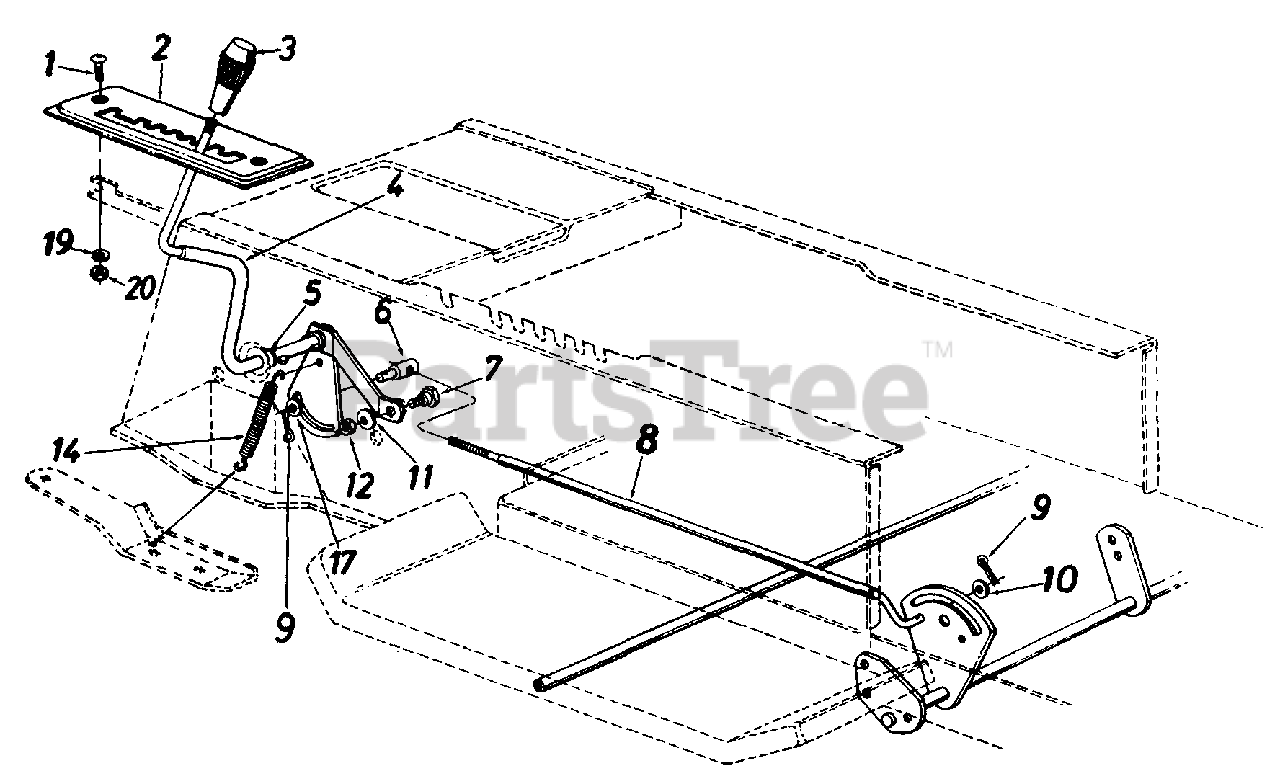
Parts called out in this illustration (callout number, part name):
1	Truss Mach. Scr. 1/4-20 x .75" Lg.
2	8-Speed Selector Plate
4	Speed Selector Lever Ass'y.
5	Flat Washer .53" I.D. x .93"
6	Ferrule 3/8-24 x .37" Dia.
7	Shoulder Bolt
8	Speed Control Link
9	Cotter Pin 3/32" Dia. x 1.0"
10	Fl-Wash. .469" I.D. x .88"
11	L-Wash. 5/16" I.D.
12	Hex Nut 5/16-18 Thd. (Gr. 5)
14	Spring .38" O.D. x 3.18" Lg.
17	Fl-Wash. .385" I.D. x .62"
19	L-Wash. 1/4" I.D.
20	Hex Nut 1/4-20 Thd. (Gr. 5)
